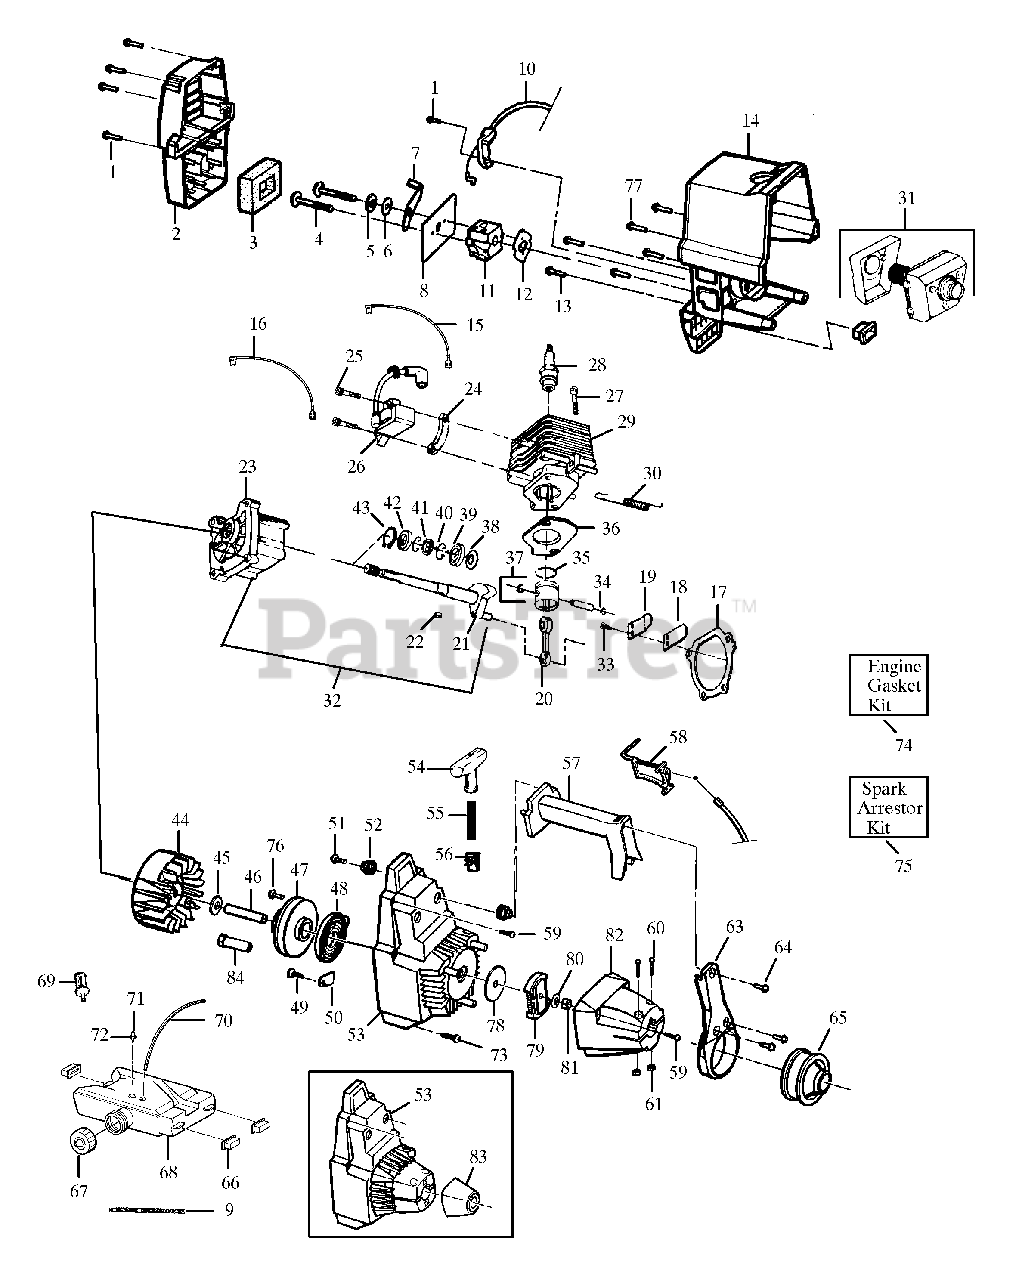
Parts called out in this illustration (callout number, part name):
2	Muffler/Air Box Cover
3	Air Filter Foam
6	Wave Washer
7	Choke Shutter
8	Air Filter Plate
10	Throttle Cable Ass'y.
11	Carburetor Models HP22, HP28, HP30T
11	Carburetor Models HP22T, HP30SB
12	Carburetor Gasket
15	Lead Wire Ass'y
16	Ground Wire Ass'y
17	Crankcase/Shroud Gasket
18	Reed Models HP22, HP22T
18	Reed Models HP28, HP30T, HP30SB
19	Reed Stop
20	Connecting Rod Ass'y. Models HP22, HP22T
20	Connecting Rod Ass'y. Models HP28, HP30T, HP30SB
21	Crankshaft Ass'y. Models HP22, HP28, HP30T
21	Crankshaft Ass'y. Models HP22T, HP30SB
22	Flywheel Key
23	Crankcase Ass'y.
24	Spacer (Models HP22 & HP22T Only)
25	Screw Models HP22, HP22T
25	Screw Models HP28, HP30T, HP30SB
26	Ignition Module
28	Spark Plug
29	Cylinder Models HP22, HP22T
29	Cylinder Models HP28, HP30T, HP30SB
30	Muffler Attachment Spring
31	Muffler Kit
32	Crankcase & Crankshaft Ass'y Models HP22, HP28, HP30T
32	Crankcase & Crankshaft Ass'y Models HP22T, HP30SB
34	Piston Pin Retainer
35	Piston Ring Models HP22, HP22T
35	Piston Ring Models HP28, HP30T, HP30SB
36	Cylinder Gasket
37	Piston Kit Models HP22, HP22T
37	Piston Kit Models HP28, HP30T, HP30SB
39	Inner Bearing
40	Retaining Ring
41	Crankshaft Seal
42	Outer Bearing
43	Crankshaft Retaining Ring
44	Flywheel Ass'y. Models HP22, HP28, HP30T
44	Flywheel Ass'y. Models HP22T, HP30SB
45	Washer Models HP22, HP28, HP30T
45	Washer Models HP22T, HP30SB
46	Flywheel Spacer-Model HP22T, HP30SB Only
47	Starter Pulley Kit
48	Starter Spring
50	Retainer
52	Handle Isolator
53	Fan Housing Models HP22, HP28, HP30T
53	Fan Housing Models HP22T, HP30SB
54	Starter Handle
55	Rope Kit
56	Rocker Switch
63	Handle Cover
65	Isolator AV
66	Fuel Tank Isolator
67	Fuel Cap Ass'y.
68	Fuel Tank Ass'y. Non-primer units
68	Fuel Tank Ass'y. Units with primer bulb
69	Fuel Pick-up Ass'y.
70	Fuel Line Kit
71	Check Valve
72	Retainer
74	Engine Gasket Kit
75	Spark Arrestor Kit
76	Screw
78	Clutch Washer-Models HP22T, HP30SB
79	Clutch Ass'y. Kit Models HP22T, HP30SB
80	Washer Models HP22T, HP30SB
81	Nut Models HP22T, HP30SB
82	Clutch Housing Models HP22T, HP30SB
83	Shaft Spacer-Model HP28 & HP30T Only
84	Drive Coupling-Models HP22, HP28 & HP30T Only
